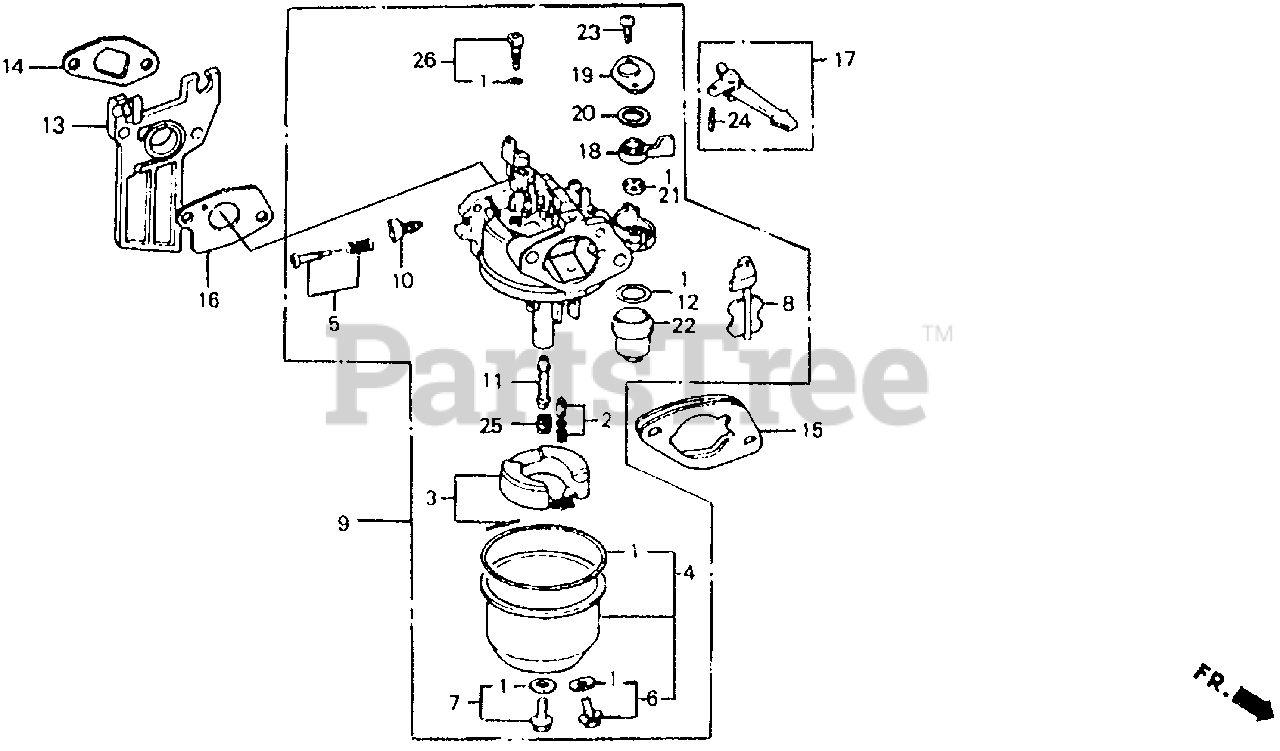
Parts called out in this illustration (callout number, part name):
1	GASKET SET
2	VALVE SET, FLOAT
3	FLOAT SET
4	CHAMBER SET, FLOAT
5	SCREW SET, PILOT
6	SCREW SET, DRAIN
7	SCREW SET B
8	CHOKE SET
9	CARBURETOR ASSY. (BE01B G)
9	CARBURETOR ASSY. (BE01C A)
9	CARBURETOR ASSY. (BE01C C)
9	CARBURETOR ASSY. (BE01C D) (NOT AVAILABLE)
9	CARBURETOR ASSY.
10	SCREW, THROTTLE STOP
11	NOZZLE, MAIN (NOT AVAILABLE)
11	NOZZLE, MAIN
12	GASKET, FUEL STRAINER CUP
13	INSULATOR, CARBURETOR
14	GASKET, INSULATOR
15	SPACER, CARBURETOR
16	GASKET, CARBURETOR
17	LEVER, CHOKE (STD)
18	LEVER, VALVE
19	PLATE, LEVER SETTING
20	SPRING, VALVE LEVER
21	GASKET, VALVE
22	CUP, FUEL STRAINER
23	SCREW, PAN (3X8)
24	PIN, SPRING (2X12)
25	JET, MAIN (#55)
25	JET, MAIN (#58)
25	JET, MAIN (#60)
25	JET, MAIN (#62)
26	JET SET, PILOT (#35)
